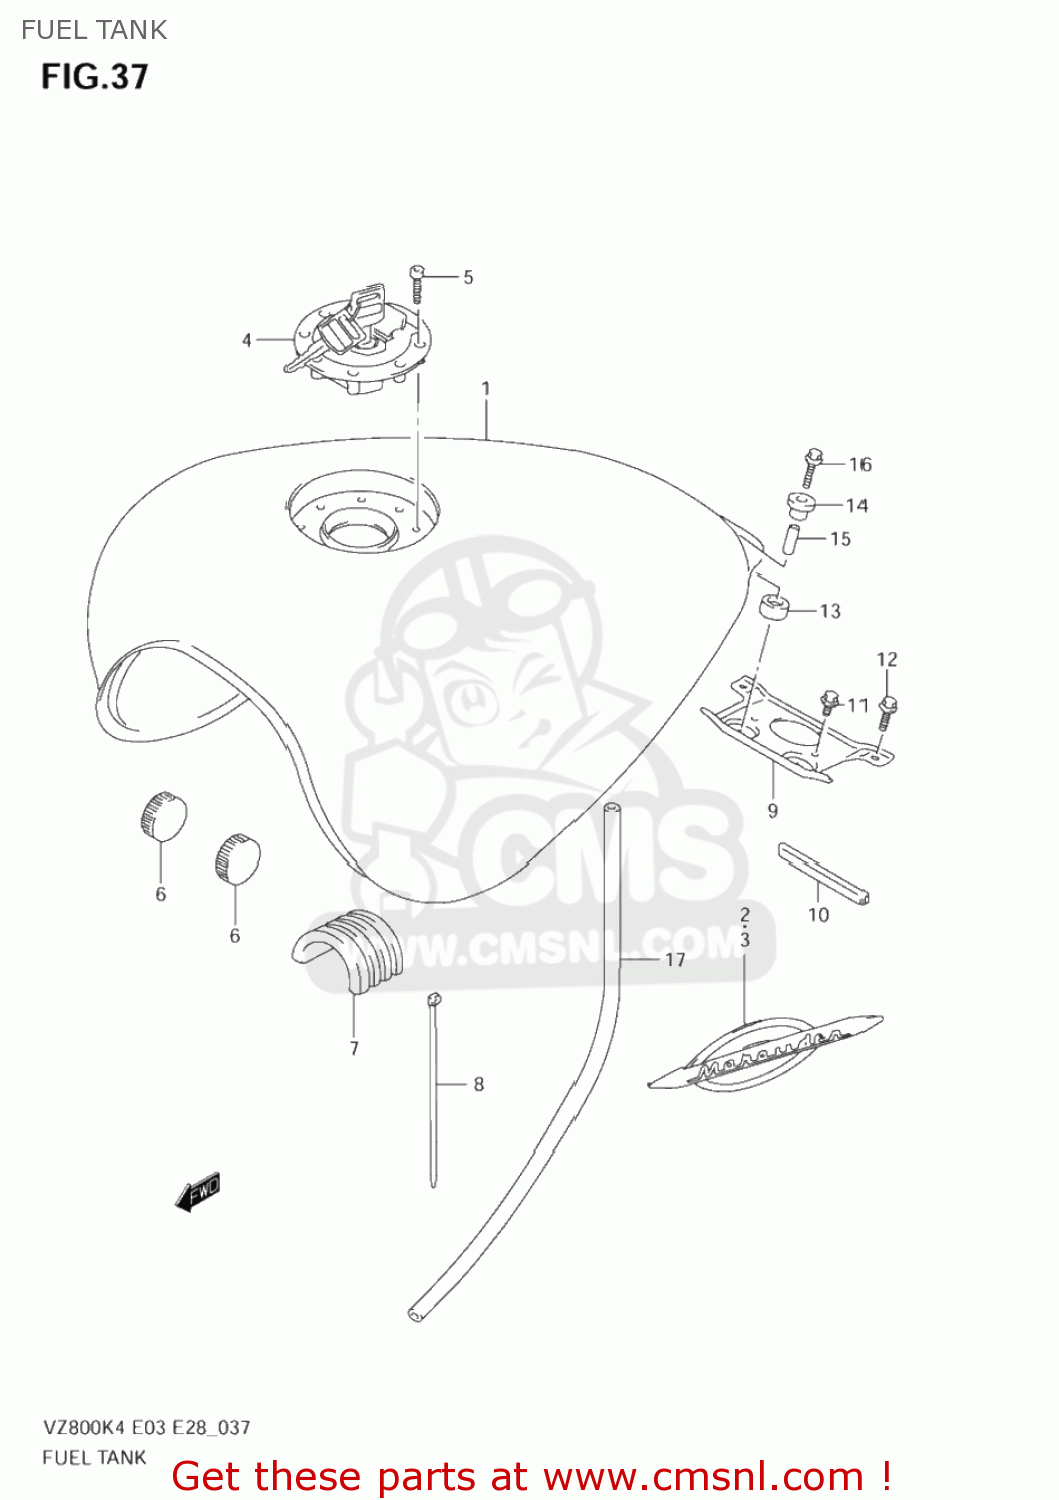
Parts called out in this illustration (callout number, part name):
1	TANK ASSY,FUEL(BLUE)
2	EMBLEM,FUEL TANK,R
3	EMBLEM,FUEL TANK,L
4	CAP SET,FUEL TANK
5	BOLT(5X20)
6	CUSHION
7	CUSHION,FUEL TANK UPR
8	CLAMP(L:250)
9	BRACKET,FUEL TANK RR
10	PROTECTOR
11	BOLT
12	BOLT
13	CUSHION,FUEL TANK RR NO.2
14	CUSHION
15	SPACER(6.5X10.5X22.5)
16	BOLT
17	HOSE,FUEL TANK DRAIN
